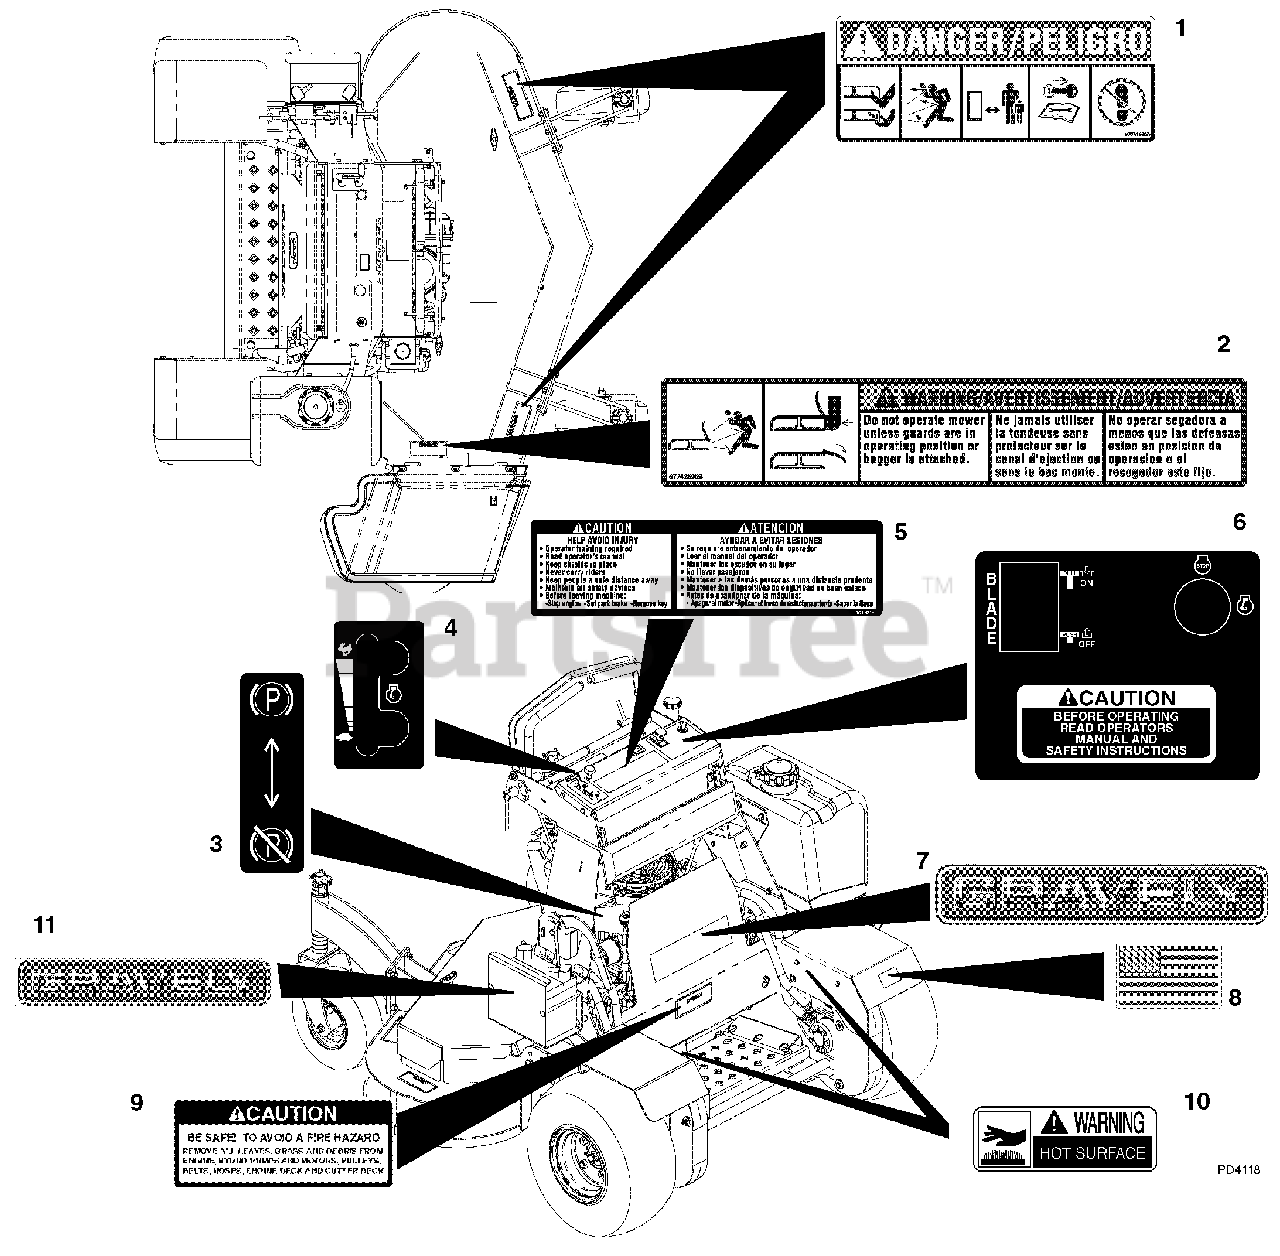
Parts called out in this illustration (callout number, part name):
1	Decal, Mower Pan Danger
2	Decal, Warning
3	Decal, Park Brake
4	Decal, Throttle
5	Decal, General Caution
6	Decal, PTO/Ignition
7	Decal, 15" Gravely Logo
8	Decal, American Flag
9	Decal, Debris
10	Decal, Warning, Hot Surface
11	Decal, Gravely Logo
